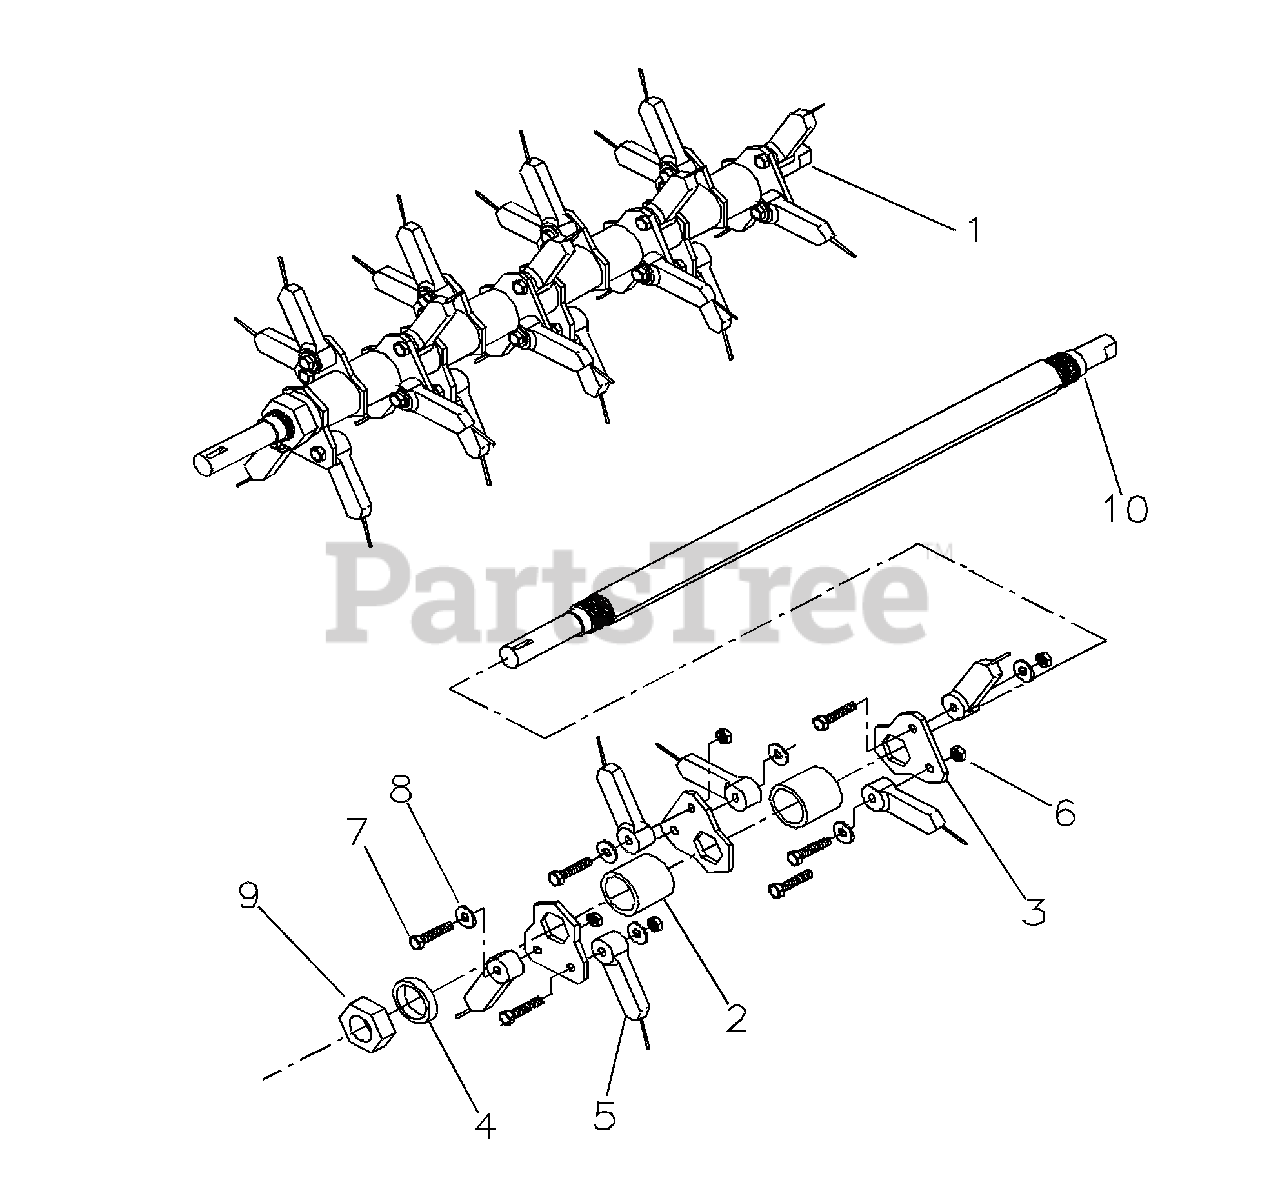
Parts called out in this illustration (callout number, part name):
1	RAKE SHAFT, COMPLETE
2	SPACER, LONG
3	PLATE, SPRING TONE
4	SPACER, SHORT
5	SPRING, TINE
6	1/4-20 NYLOC NUT
7	1/4 X 1-1/4 HCS
8	1/4 FLAT WASHER
9	JAM NUT W/SET SCREW
10	SHAFT, SPRING TINE
